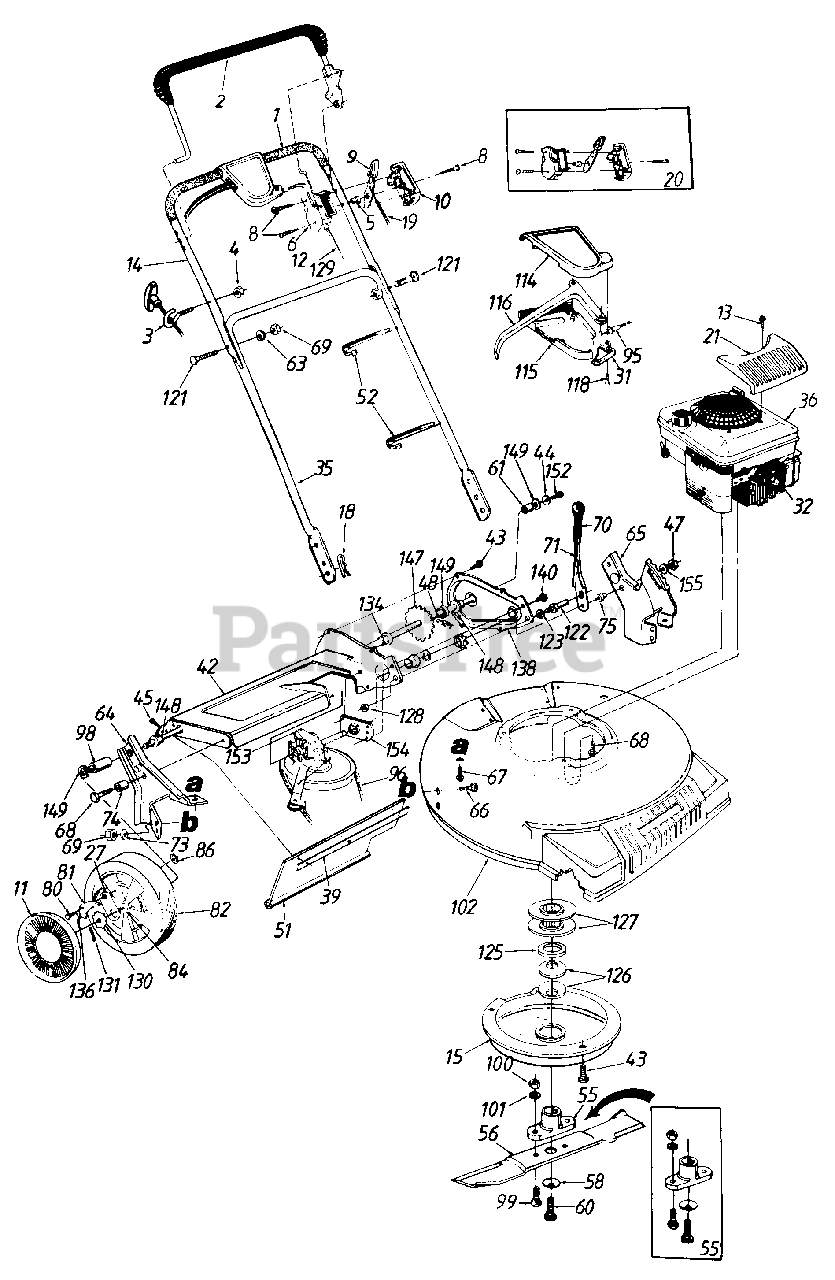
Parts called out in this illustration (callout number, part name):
1	Grip
2	Control Handle Ass'y.
3	Rope Guide Bolt
4	Hex L-Nut 1/4-20 Thd.
5	Control Disc Pin
6	Clutch Panel Half
8	Truss Mach Scr. #12 x 1.5" Lg.
9	Throttle Control Lever
10	Control Panel Half
11	Hub Cap
12	Throttle Control Label
13	Truss Hd AB-Tap Scr. #6 x .62" Lg.
14	Upper Handle
19	Throttle Control Wire 51" Lg.
20	Kit Control Housing Comp.
21	Engine Cover
27	Pawl Plate
31	S.P. Control Cover
32	Spark Plug Insulator
35	Lower Handle
36	Engine
39	Retaining Strip
42	Chain Axle Ass'y.
43	Hex B-Tap Scr. 1/4" x .38"
44	Bell-Wash. 1/4" I.D.
45	Hex AB-Tap Scr. 1/4 x .62"
47	Hex Patch L-Nut 3/8-24 Thd.
48	#48 Chain .500" Pitch x 38 Links
51	Rear Flap 3.75" x 17.30" Lg.
52	Cable Tie
55	Blade Adapter Kit
56	21" Mulching Blade
58	Bell-Wash. .47" I.D. x 1.14" O.D.
60	Hex Bolt 7/16-20 x 2.5"
61	Spacer.513" I.D.
63	L-Wash. 5/16" I.D.
64	R.H. Handle Wheel Brkt. Ass'y.
65	L.H. Handle Wheel Brkt. Ass'y.
66	Carriage Bolt 5/16-18 x .62
67	Hex B-Tap Scr. 5/16-18
68	Hex TT-Tap Scr. 3/8-16
69	Hex Nut 5/16-18 Thd.
71	Height Adj. Lever
73	Bell-Wash. 5/16" I.D.
74	Spacer.383" I.D.
75	Shld. Spacer.5" Dia.
80	Shld. Scr. .342" Dia. x .268
81	Pawl
82	Wheel Ass'y. Comp. Rear
84	Sleeve Bearing 1/2" I.D.
86	Flat Nut 1/4-20 Thd.
95	S.P. Cable 44" Lg.
96	"V"-Belt
98	Sleeve.526" I.D.
99	Hex Bolt 3/8-24 x 1.0" Lg.
100	Hex Nut 3/8-24 Thd.
101	L-Wash. 3/8" I.D.
115	Self-Propelled Control Cover
116	Control Lever
118	Fl-"C"-Sunk Hd. Tap Scr. #10 x 75" Lg.
121	Curved Carr. Bolt 5/16-18 x 1.38" Lg.
122	Shld. Pin 1.43" Lg.
123	L-Wash. 3/8" I.D.
125	Crankshaft Spacer
126	Bell-Wash. 1.01" I.D.
127	Serrated Pulley Half
128	Hex Jam Nut 3/8-24 Thd.
129	Control Cable 39"
130	Ratchet Wheel 1.62" O.D.
131	Cotter Pin 1/8" Dia. x 1
134	Hex Flange Bearing
136	Spring Nylon
147	Rear Shaft Ass'y. 21.44" Lg.
148	Hex Flange Brg. .506" I.D.
149	Fl-Wash. .531" I.D. x .930"
152	Hex Bolt 1/4-20 x .62" Lg. (Grade 5)
153	Transmission Comp.
155	Fl-Wash. .885" I.D. x .37" O.D.
